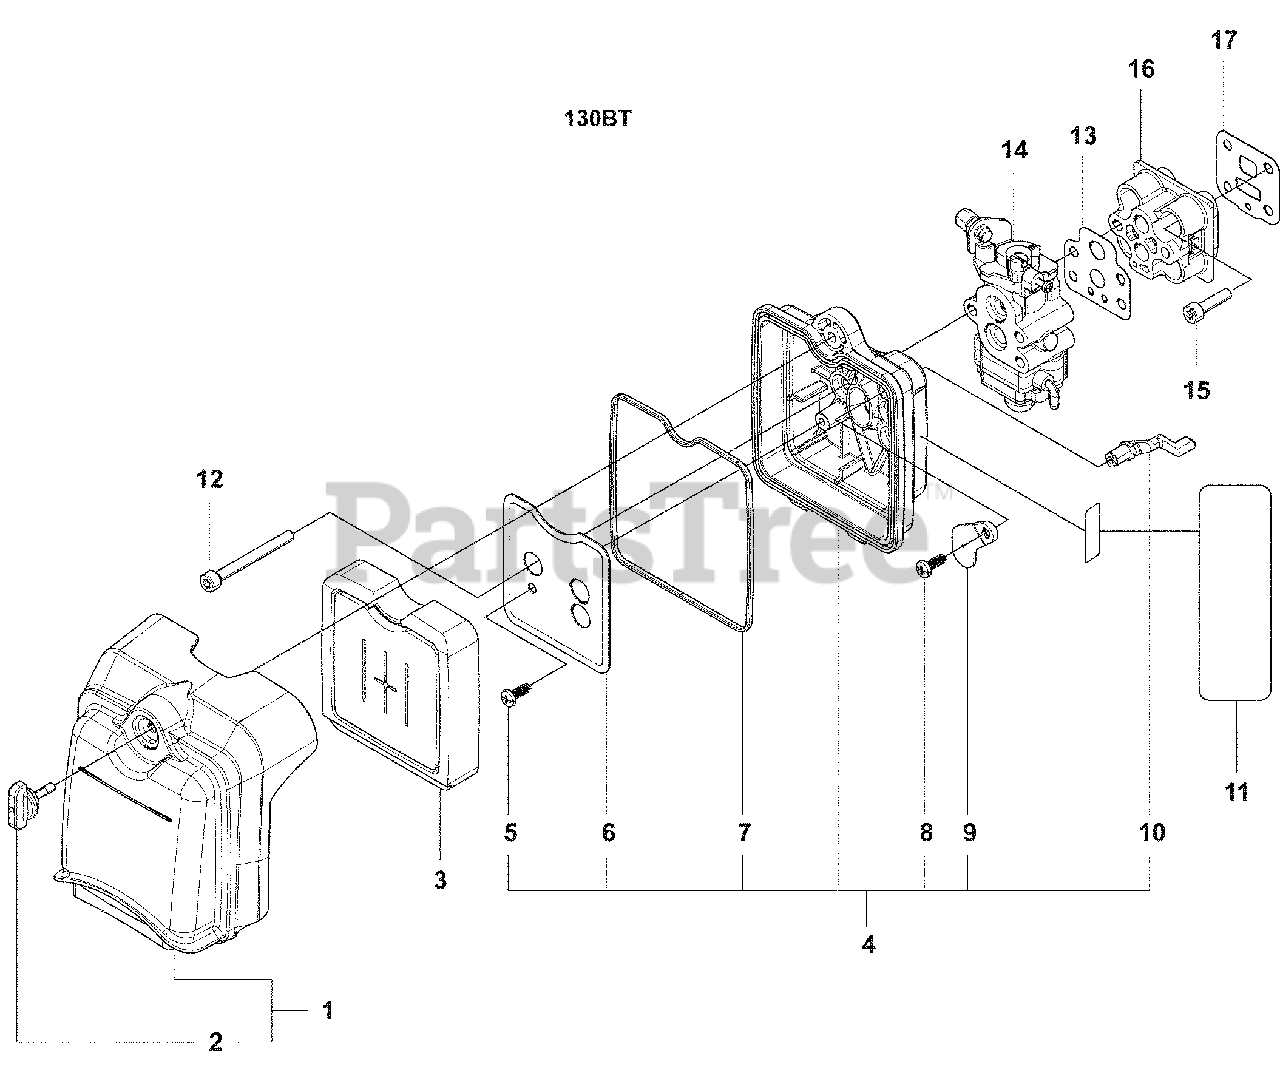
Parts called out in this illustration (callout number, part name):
3	Air Filter Element
4	Body and Screen
11	Choke Label
14	Carburetor Assembly
15	Torx Bolt
17	Insulator Gasket
